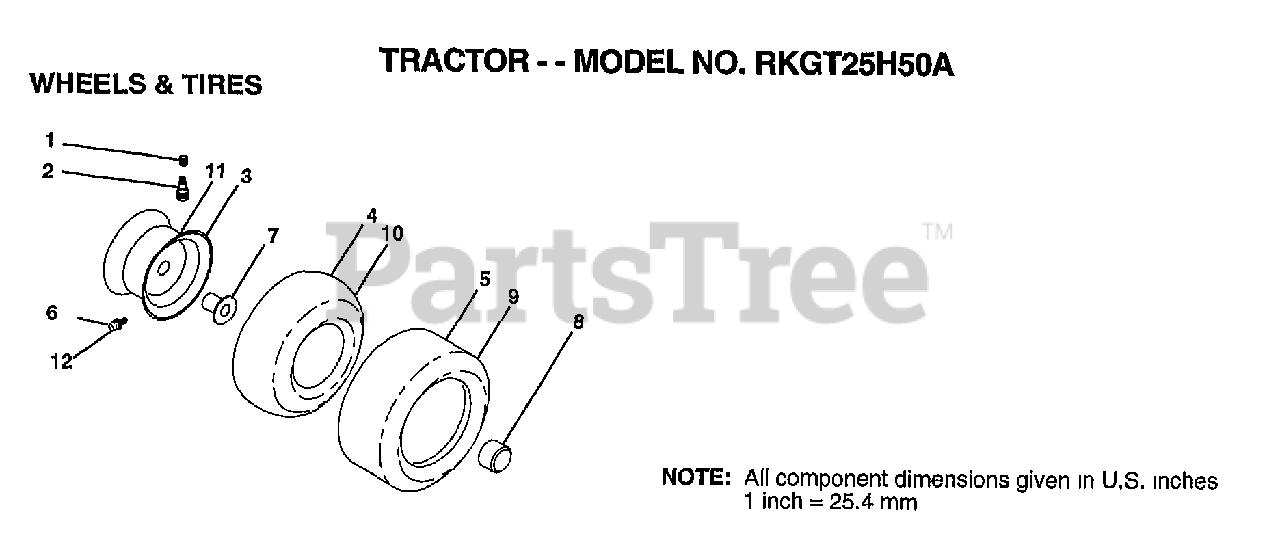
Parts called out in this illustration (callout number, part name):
1	VALVE CAP
2	VALVE STEM LT
3	"RIM ASM 8"" FRT"
4	TUBE.16X6.5/7.5-8
6	FITTING LT
7	"FLANGE, BEARING"
8	HUB CAP
10	TUBE.23X8/10-12
11	"RIM ASM 12"" REAR"
12	ZERK FITTING M
